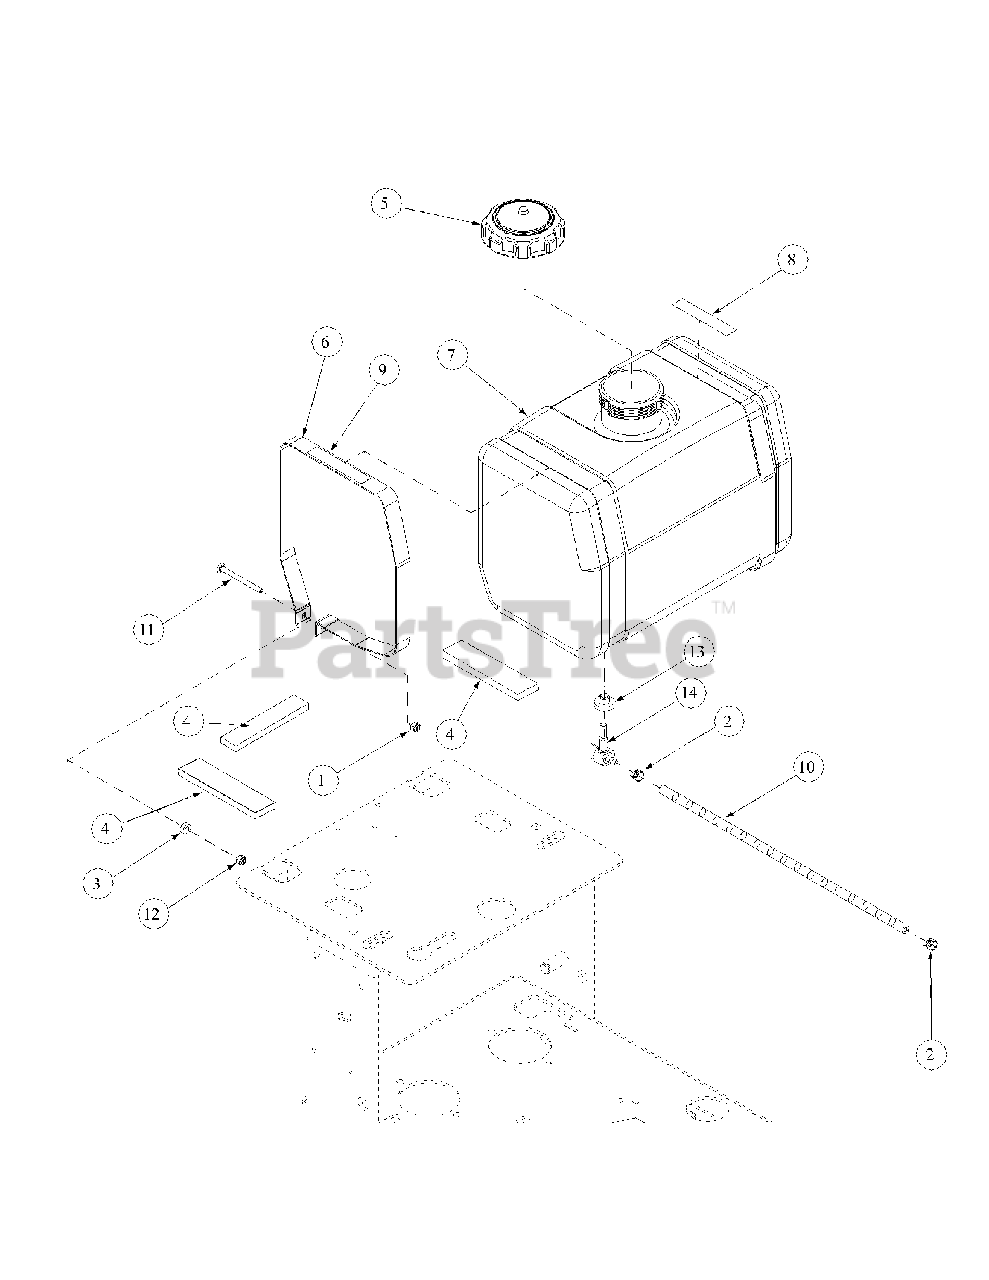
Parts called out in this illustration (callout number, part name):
1	Lock Nut, Nylon Insert, 1/4-2
2	Uni-Clamp
4	Stop Pad, Rubber
5	Fuel Cap, 3.5
6	Fuel Tank Strap
7	Fuel Tank
8	Mower Warning Label, Turn off Engi
9	Mower Instruction Label, Fuel Valve
10	Fuel Hose, 18"
11	Carriage Bolt, 1/4-20 x 3.00
13	Grommet Fuel Tank
14	Shutoff Valve
